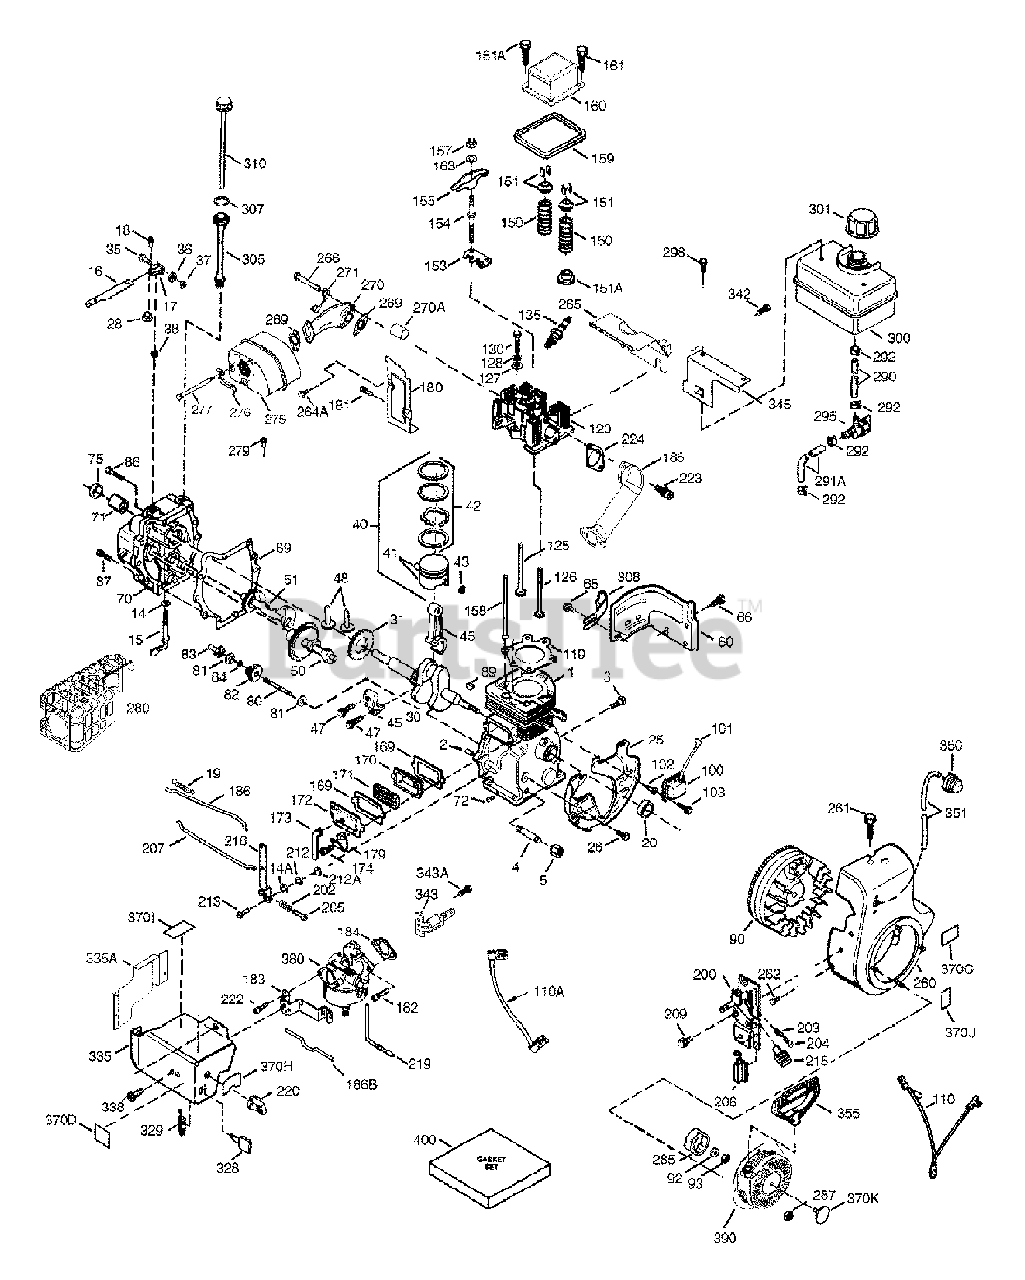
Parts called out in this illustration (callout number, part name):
1	Cylinder
2	Dowel Pin
3	Screw, 1/4-20 x 1/2"
4	Oil Drain Extension
5	Extension Cap
15	Governor Rod
16	Governor Lever
17	Governor Lever Clamp
18	Screw, T-15, 8-32 x 7/16"
19	Throttle Spring
25	Blower Housing Baffle
26	Screw, 1/4-20 x 19/32"
28	Lock Nut, 8-32
30	Crankshaft
31	Counterbalance Gear
35	Screw, 10-32 x 3/4"
36	Lock Washer
37	Lock Nut, 10-32
38	Retaining Ring
40	Piston, Pin & Ring Set (Std.)
40	Piston, Pin & Ring Set (.010" OS)
40	Piston, Pin & Ring Set (.020" OS)
41	Piston & Pin Ass'y (Std.)
41	Piston & Pin Ass'y (.010" OS)
41	Piston & Pin Ass'y (.020" OS)
42	Ring Set (Std.)
42	Ring Set (.010" OS)
42	Ring Set (.020" OS)
43	Piston Pin Retaining Ring
45	Connecting Rod Ass'y
47	Connecting Rod Bolt
48	Valve Lifter
50	Camshaft (MCR)
51	Counterbalance Weight
60	Blower Housing Extension
65	Screw, 10-24 x 9/16"
66	Screw, T-30, 1/4-20 x 1/2"
69	Cylinder Cover Gasket
70	Cylinder Cover
71	Crankshaft Bushing
80	Governor Shaft
82	Governor Gear Ass'y
83	Governor Spool
84	Retaining Ring
86	Screw, 1/4-20 x 1-3/16"
87	Screw, 1/4-20 x 1-11/16"
89	Flywheel Key
90	Flywheel (W/Ring Gear)
92	Lock Washer
93	Flywheel Nut
100	Solid State Ignition
101	Spark Plug Cover
102	Solid State Mounting Stud
103	Screw, T-15, 10-24 x 15/16"
110	Ground Wire
110A	Ground Wire
119	Cylinder Head Gasket
120	Cyinder Head
125	Exhaust Valve (Std.)
125	Exhaust Valve (1/32" OS)
126	Intake Valve (Std.)
128	Belleville Washer
130	Screw, 5/16-18 x 2-1/2"
135	Spark Plug (RN4C)
150	Valve Spring
151	Valve Spring Keeper
151A	Intake Valve Seal
153	Push Rod Guide
154	Rocker Arm Stud
155	Rocker Arm
159	Rocker Arm Cover Gasket
160	Rocker Arm Cover
161	Screw, T-30, 1/4-20 x 1/2"
161A	Valve Cover Mounting Stud
163	Lock Washer
169	Valve Cover Gasket
170	Breather Body
171	Breather Element
172	Valve Cover
173	Breather Tube
174	Screw, 10-24 x 1/2"
180	Blower Housing Extension
181	Lock Nut, 10-32
182	Screw, T-30, 1/4-20 x 27/32"
183	Choke Bracket
184	Carburetor To Intake Pipe Gasket
185	Intake Pipe
186	Governor Link
186B	Choke Spring
200	Control Bracket
202	Compression Spring
203	Compression Spring
204	Screw, T-10, 5-40 x 7/16"
205	Screw, T-10, 6-32 x 41/64"
207	Choke Link
209	Screw, 10-32 x 1/2"
213	Screw, 10-32 x 5/8"
215	Control Knob
216	R.P.M. Adjusting Lever
219	Choke Rod
220	Ckoke Knob
222	Screw, 10-32 x 1/2"
223	Screw, T-30, 5/16-18 x 7/8"
224	Intake Pipe Gasket
260	Blower Housing
261	Screw, 1/4-20 x 5/8"
262	Screw, T-40, 5/16-24 x 21/32"
264A	Screw, T-30, 1/4-20 x 1/2"
265	Cylinder Head Cover
266	Screw, 5/16-18 x 1-9/32"
269	Exhaust Gasket
270A	Exhaust Port Liner
271	Locking Plate (Manifold)
276	Locking Plate
277	Screw, 5/16-18 x 4-1/2"
279	Screw, 10-32 x 5/16"
280	Heat Shield
285	Starter Cup
287	Nut & Lock Washer, 1/4-28
290	Fuel Line
292	Fuel Line Clamp
298	Screw, 1/4-15 x 3/4"
300	Fuel Tank
301	Fuel Cap
305	Oil Fill Tube
308	Fill Tube Clip
314	Screw, 1/4-20 x 3/4"
328	Ignition Keys
335	Carburetor Cover
335A	Carburetor Cover
338	Screw, 10-32 x 1/2"
342	Screw, 5/16-18 x 7/8"
343	Key Switch Bracket
343A	Screw, 10-32 x 23/64"
345	Heat Baffle
350	Primer Ass'y
351	Primer Line
355	Starter Handle
370C	Primer Decal
370D	Caution Decal
370I	Warning Decal
370J	Throttle Decal
370K	Starter Decal
380	Carburetor
390	Rewind Starter
400	Gasket Set
